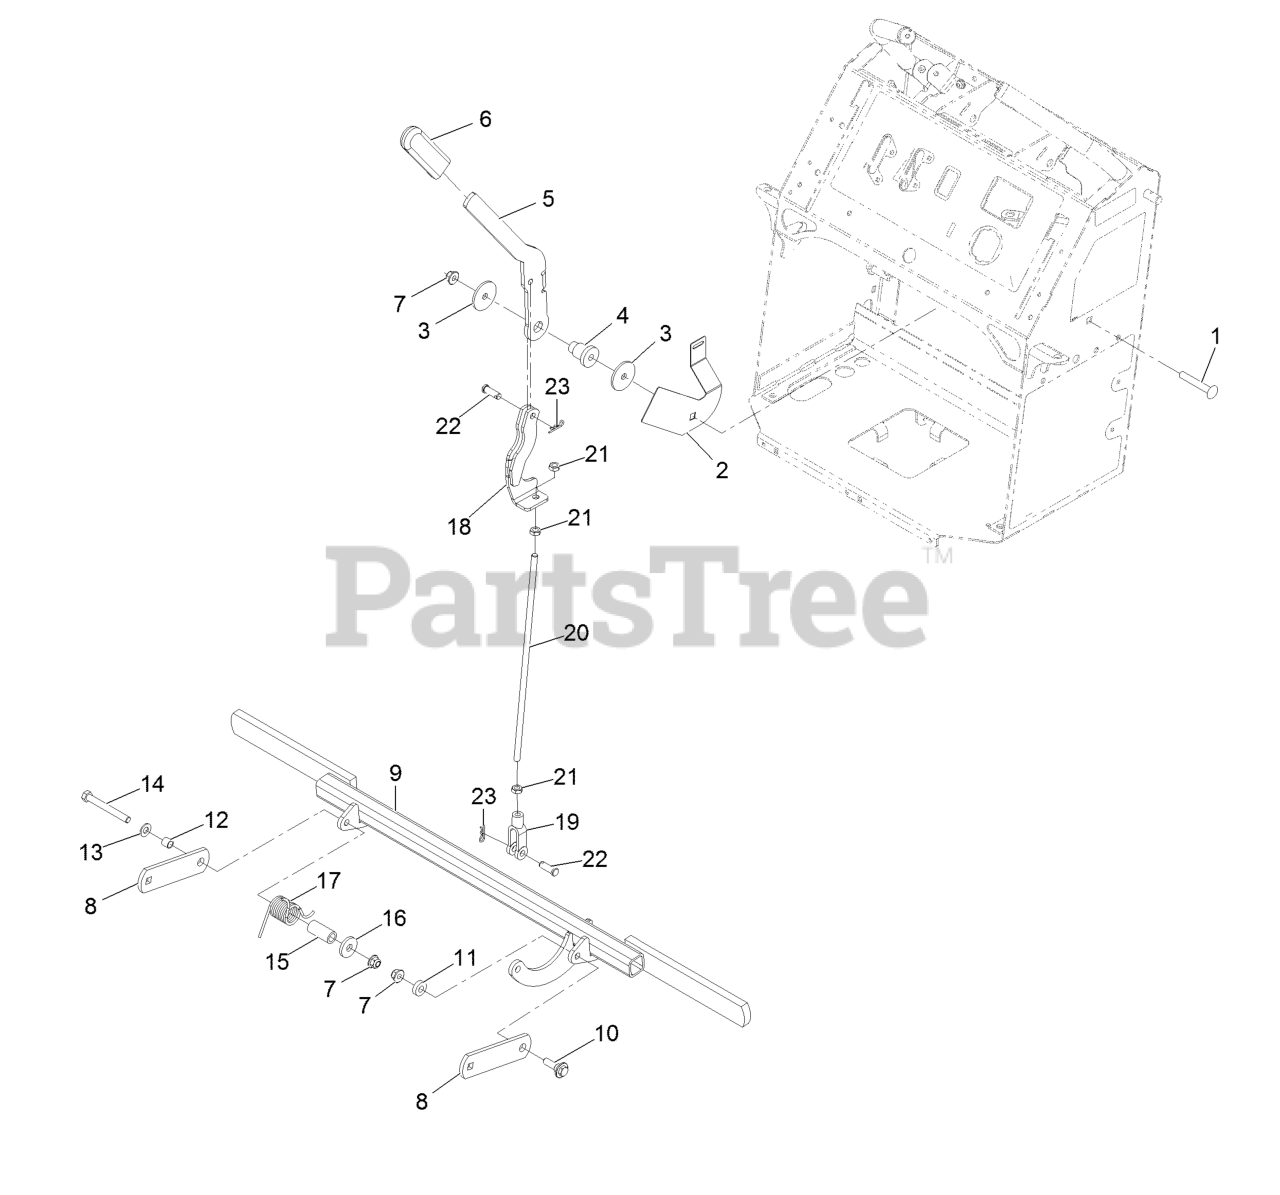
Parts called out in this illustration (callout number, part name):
1	Bolt-Carriage 3/8-16 X 2 1/2
2	Plate-Switch, Brake
3	Washer-Rebound
4	Mount-Pulley
5	Lever-Brake
6	Grip-Lever
7	Nut-Nyloc 3/8-16 Flg
8	Support-Brake
9	Bar-Brake
10	Screw-Shoulder 3/8-16 X 1.295
11	Spacer
13	Washer-3/8 SAE
14	Screw-HH 3/8-16 X 3-1/4
16	Spring-Torsion
18	Arm-Brake
19	Yoke-Linkage, Brake
20	Rod-Brake
21	Nut-Jam 3/8-24
22	Pin-Clevis 3/8 X 1 1/6
23	Pin-Cotter
